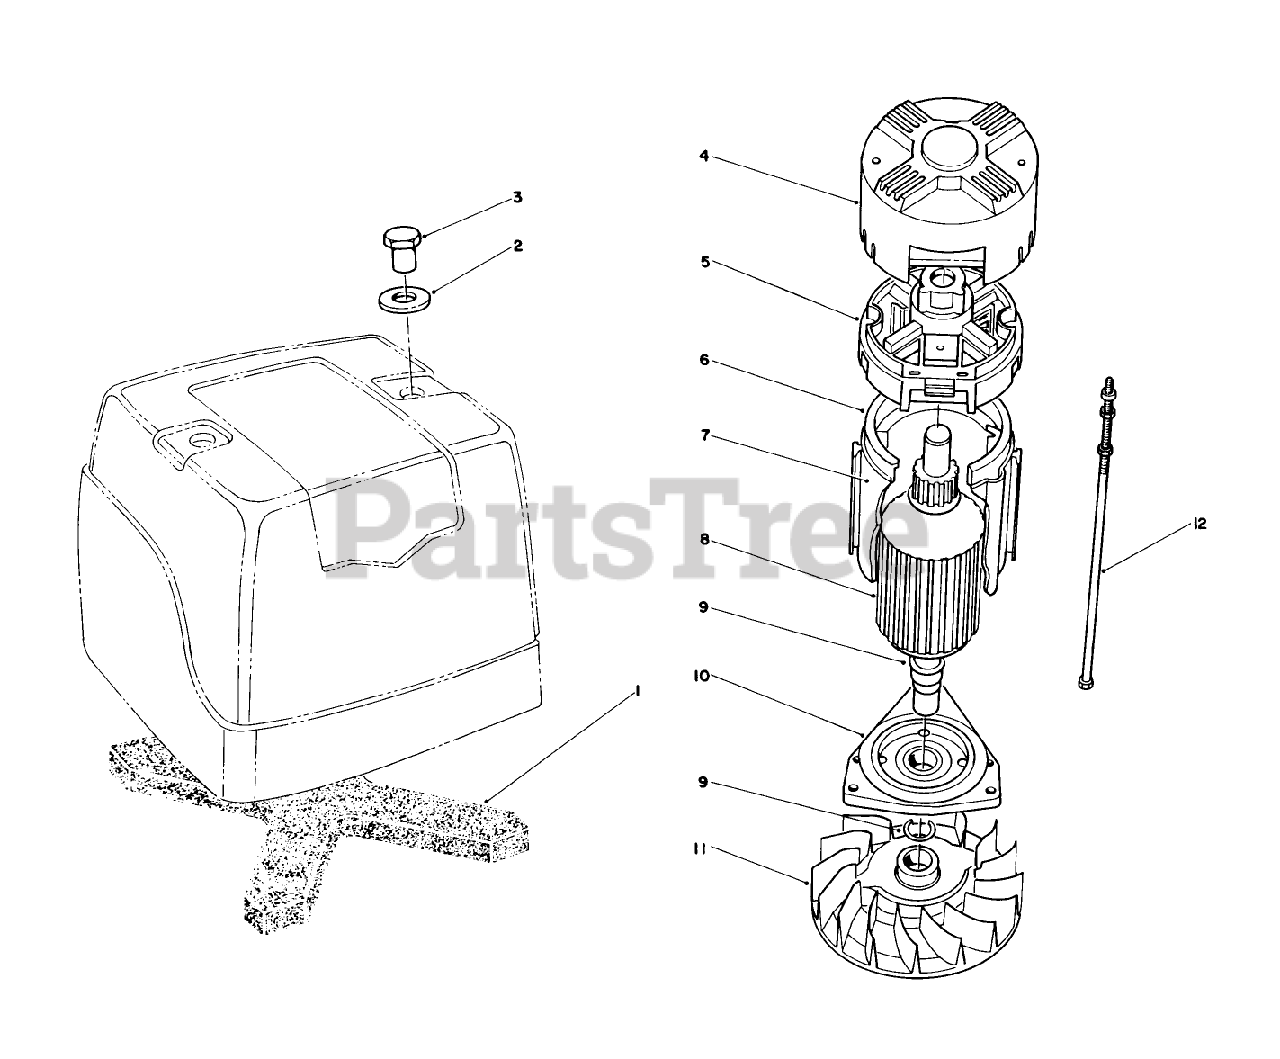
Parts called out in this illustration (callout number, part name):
1	Filter
2	Washer
3	Nut-Hex
4	End Cap-Brush
5	Brush Box Group (Includes: 490834 Brush Pin Group)
6	Housing Assembly
7	Insulator Group-Housing
8	Armature Group
9	Ring-Retaining
10	Spacer
12	Bolt-Thru (Includes Two Sets)
